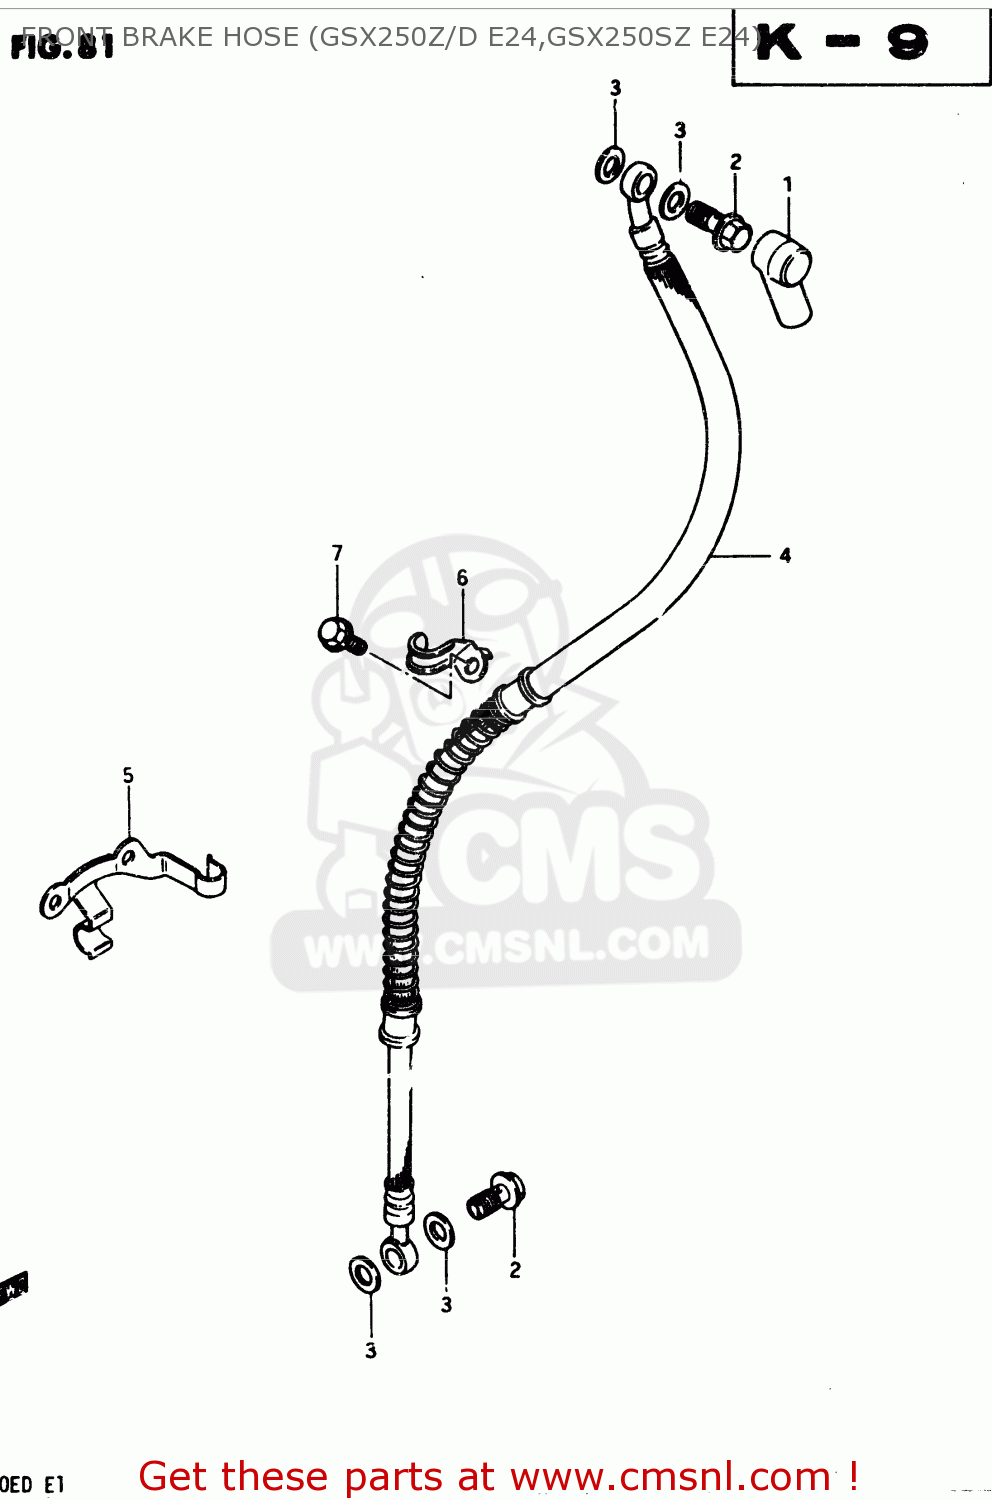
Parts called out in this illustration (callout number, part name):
1	BOOT,MASTER CYLINDER
2	BOLT,UNION
3	WASHER
4	HOSE,FR BRAKE
5	CLAMP,FRONT BRAKE HOSE
6	GUIDE,BRAKE HOSE NO.3
7	BOLT
